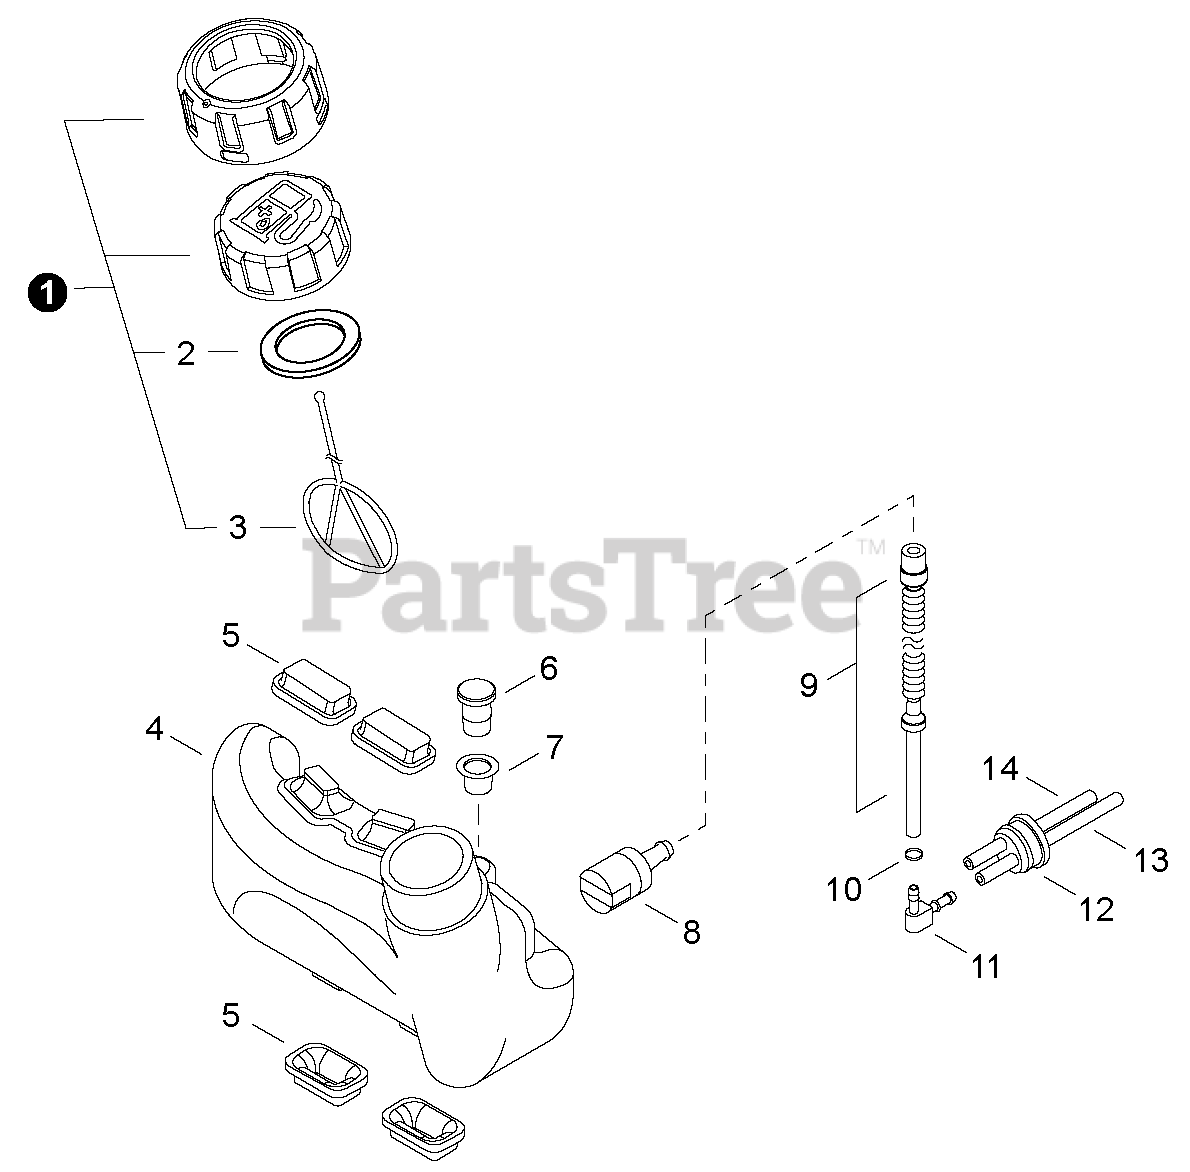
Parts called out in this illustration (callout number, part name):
1	CAP ASSY, FUEL
2	GASKET, FUEL CAP
3	CONNECTOR, CAP L= 123
4	TANK, FUEL
5	CUSHION
6	VENT ASSY
7	GROMMET, FUEL
8	FILTER, FUEL
9	PIPE, FUEL
10	CLIP Ø6.5 MM
11	CONNECTOR, PIPE
12	GROMMET, FUEL
13	PIPE, FUEL 3×5×83 BLACK
14	PIPE, FUEL 3×6×85 CLEAR
